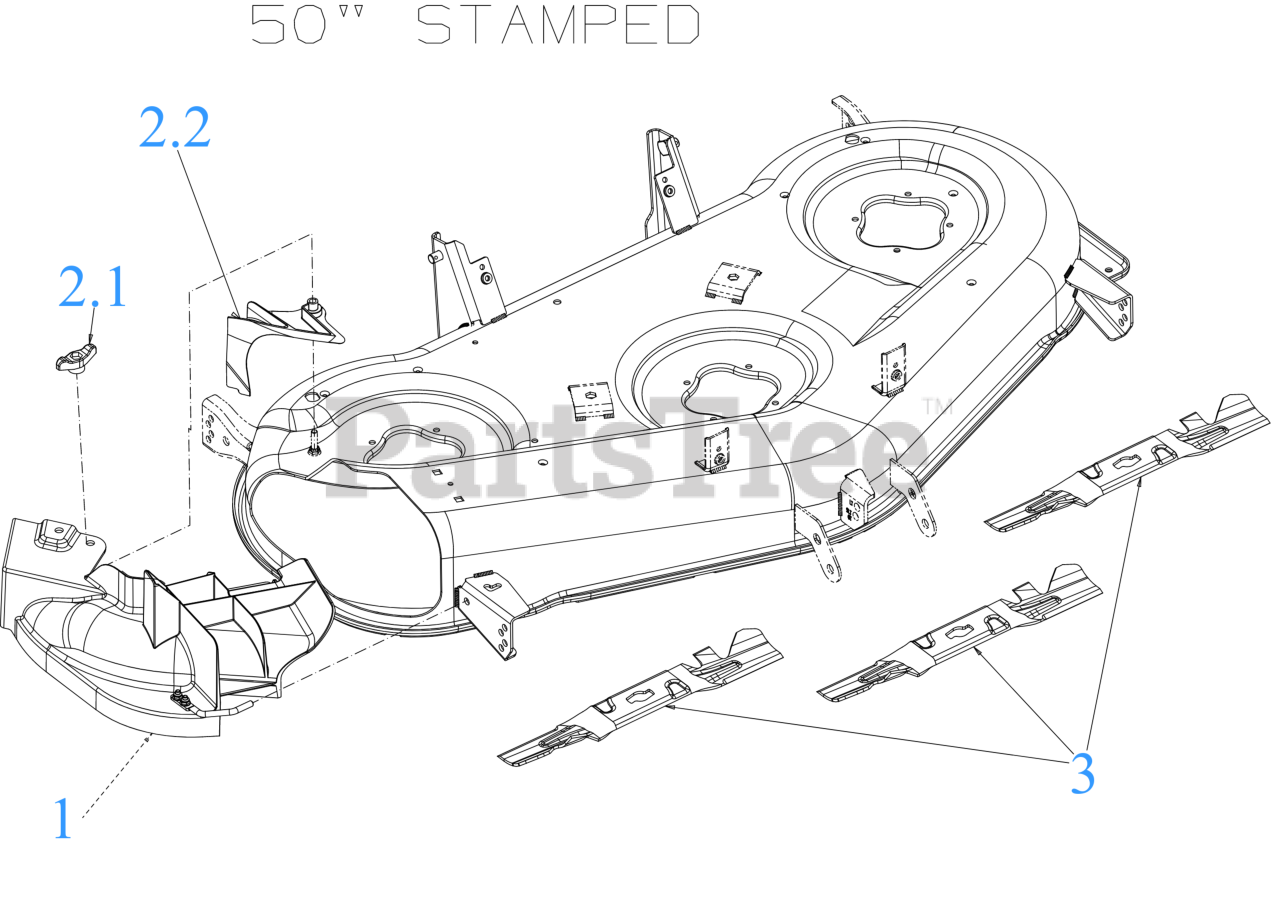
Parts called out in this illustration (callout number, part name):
1	MULCH PLUG ASSEMBLY
1	FLANGE LOCK NUT
1	MULCH PLUG MOUTING ROD
1	SCREW 1/4-20X.75 GR5
1	FLAT WASHER
2.1	WING KNOB 5/16-18
2.2	CHUTE ADAPTER
3	17.271" XTREME BLADE (2IN1) (S SHAPE CENTER HOLE)
